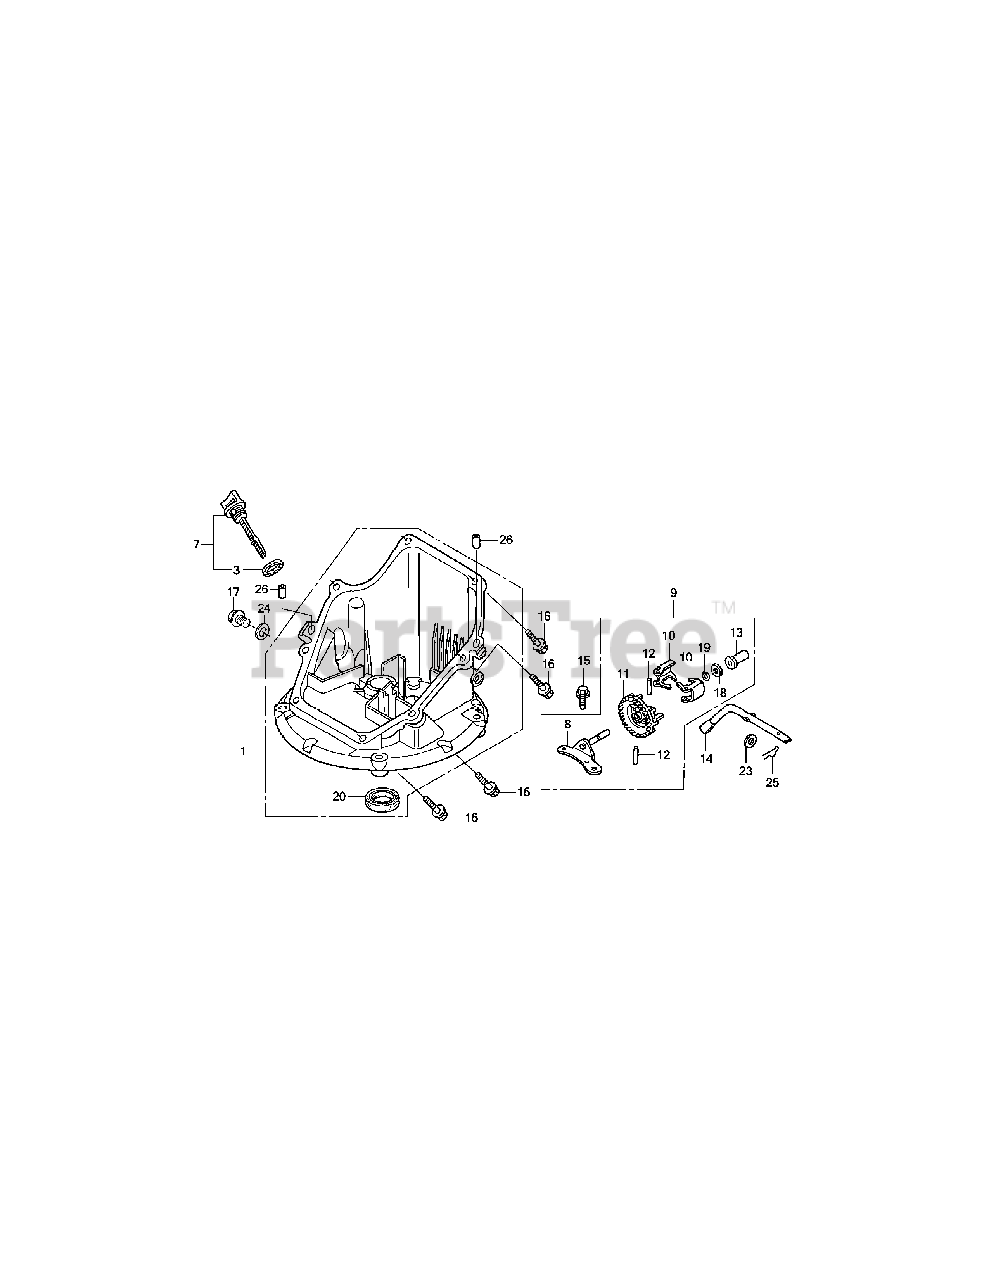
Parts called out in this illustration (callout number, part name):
1	Oil Pan Assembly
3	Oil Filler Cap Gasket
7	Oil Level Gauge Assembly
8	Governor Holder Shaft
9	Governor Assembly
10	Governor Weight
11	Governor Weight Holder
12	Governor Weight Pin
13	Governor Slider
14	Governor Arm Shaft
15	Flange Bolt, 6 x 14
16	Flange Bolt, 6 x 25
17	Drain Plug Bolt
18	Thrust Washer, 6mm
19	Governor Holder Clip
20	Oil Seal, 28 x 41.25 x 6
23	Plain Washer, 6mm
24	Drain Plug Washer, 12mm
25	Lock Pin, 8mm
26	DowelPin,8x20
